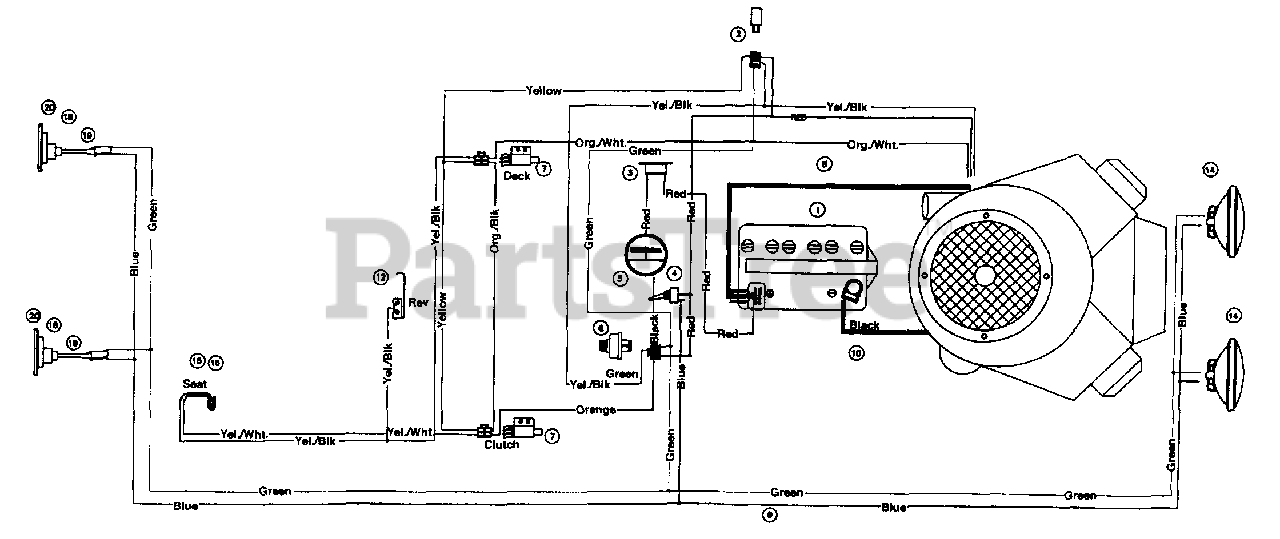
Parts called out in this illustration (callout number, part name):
1	Battery
2	Bosch Relay
3	Circuit Breaker 20 Amp
4	Light Switch
5	Ammeter
6	Ignition Switch
7	Interlock Switch
8	Wire 6 Gage Red 32.5" Lg.
9	Harness
10	Wire 6 Gage Black 14" Lg.
12	Reverse Safety Switch
14	Bulb, Headlight
15	Seat Safety Switch
16	Seat Safety Switch
18	Tail Light
19	Tail Light Harness
20	Bulb, Tail Light
